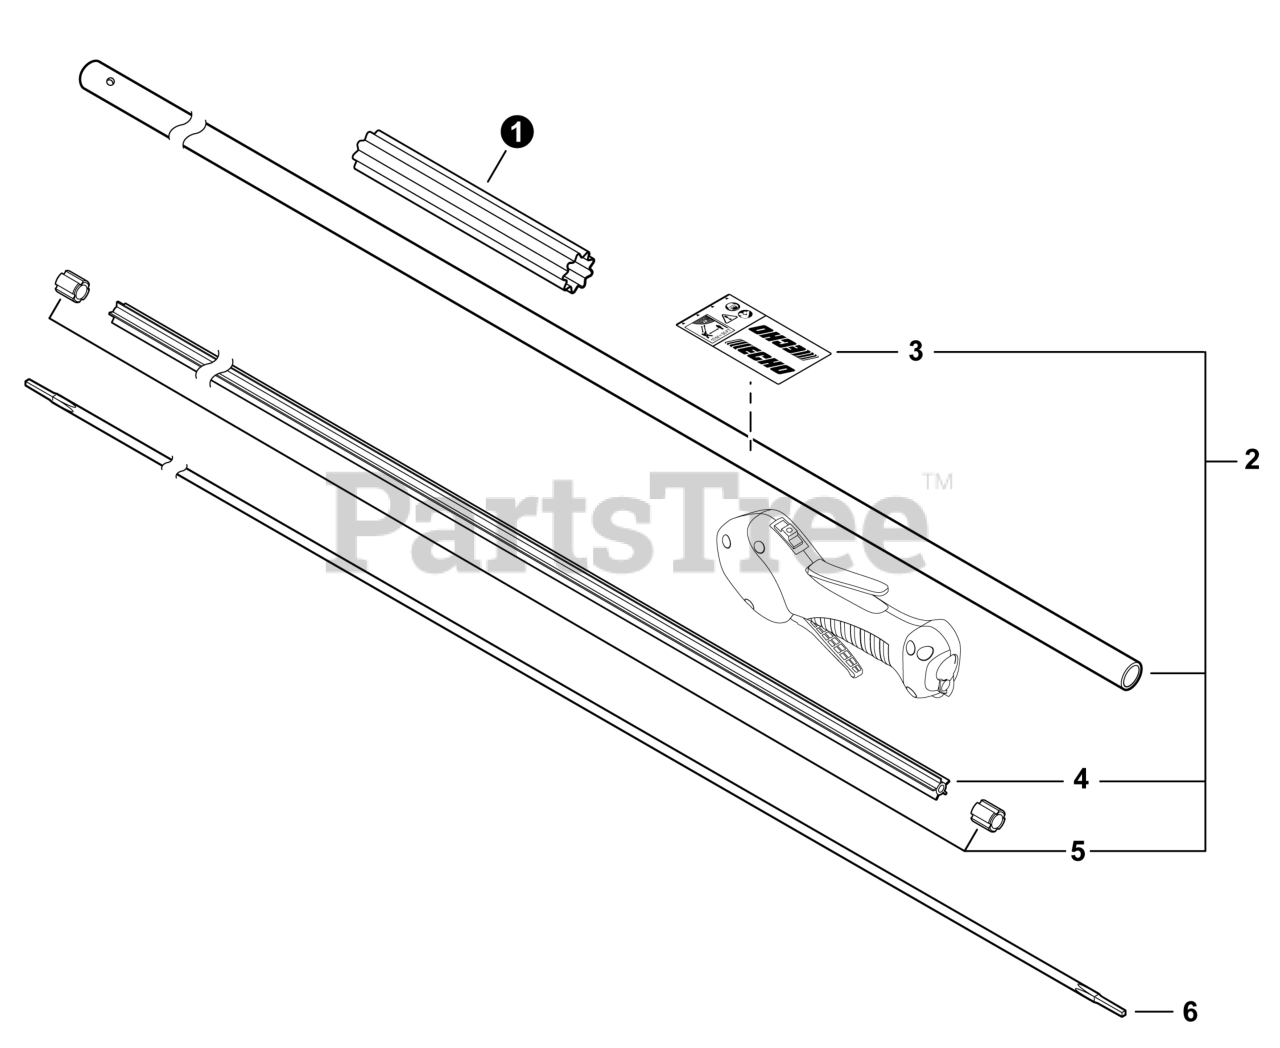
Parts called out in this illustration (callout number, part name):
1	STOPPER, HANDLE
2	MAIN PIPE ASSY
3	LABEL - CAUTION
4	LINER - FLEXIBLE
6	DRIVESHAFT - FLEXIBLE
